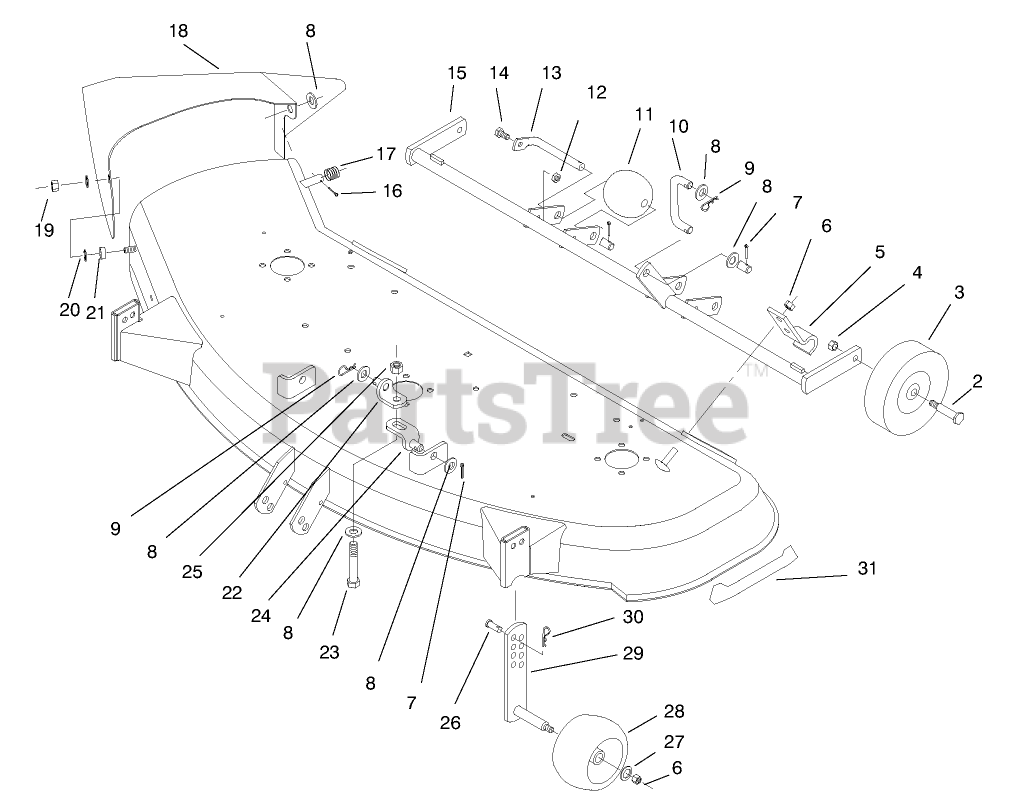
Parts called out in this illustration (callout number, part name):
1	BOLT-CARR
1	BEARING
2	BOLT-SHOULDER
3	WHEEL
4	NUT-HEX
5	BRACKET-PIVOT
6	NUT-LOCK, NI
7	PIN-COTTER
8	WASHER-FLAT
9	PIN-COTTER, HAIR
10	LINK-REAR
11	ROLLER
12	NUT-LOCK, NI
13	SHAFT-ROLLER
14	SCREW-HH
15	SUPPORT-GAGE WHEEL
16	PIN-COTTER
17	SPRING-DEFLECTOR
18	Chute / Decal Asm
19	NUT-HJ
20	WASHER
21	BUSHING-PIVOT
22	BRACKET-LIFT, UPPER
23	SCREW-HH
24	BRACKET-LIFT, LOWER
25	NUT-JAM
26	PIN-CLEVIS
27	WASHER-FLAT
28	WHEEL-GAGE
29	GAGE-WHEEL
30	PIN-HAIR
31	DECAL-RECYCLER
